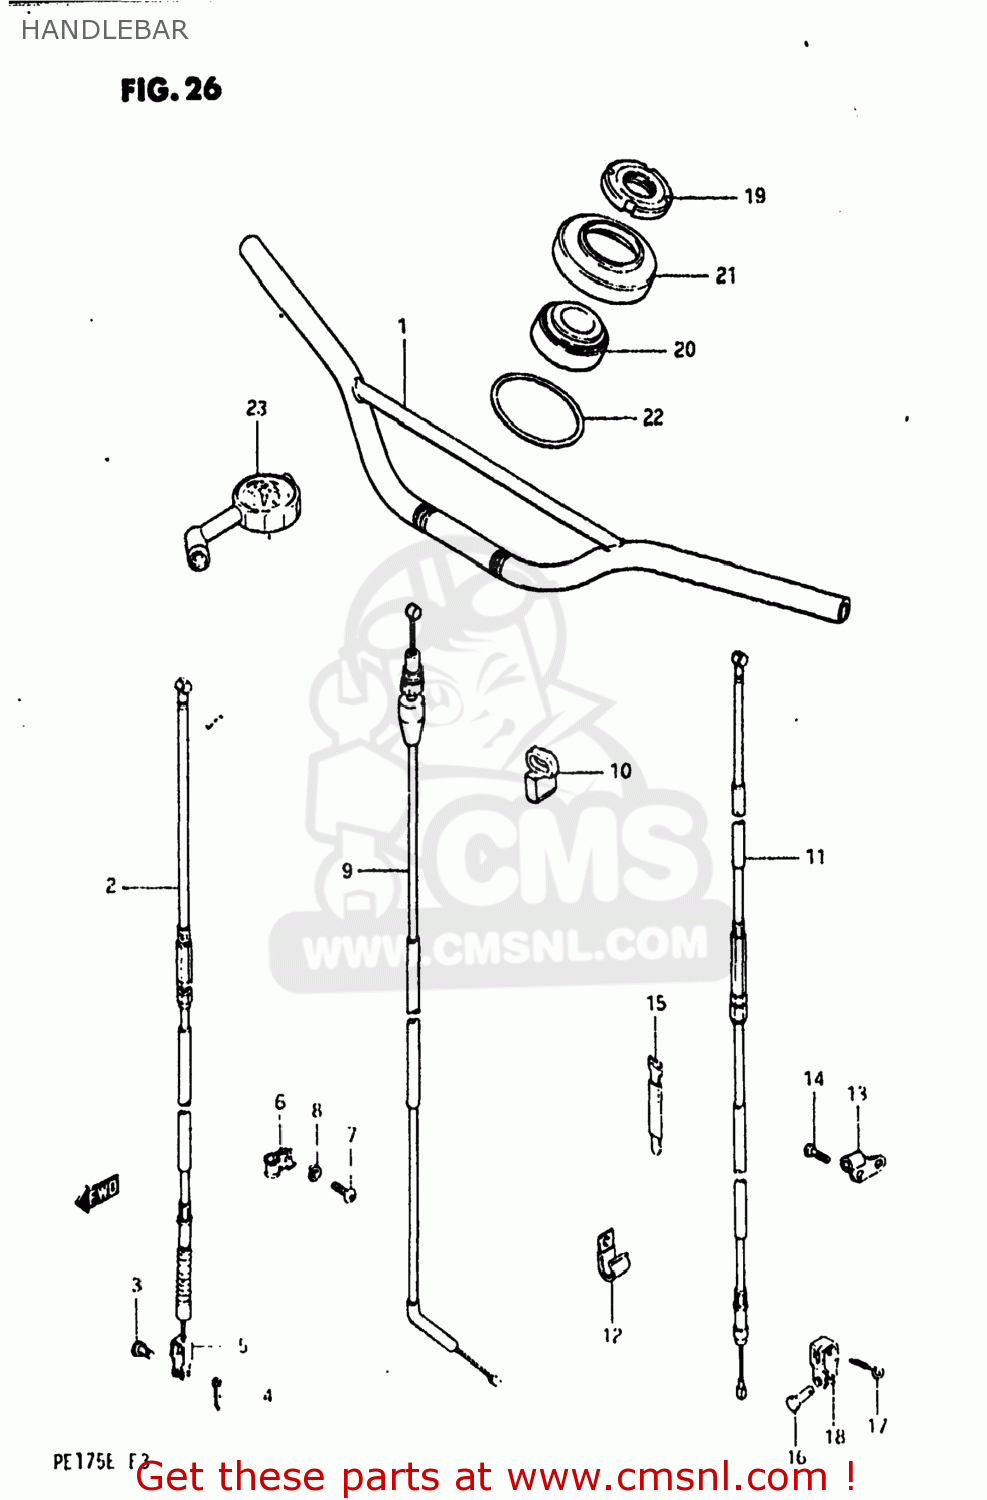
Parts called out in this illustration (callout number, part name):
1	HANDLEBAR
2	CABLE,FR BRAKE
3	PIN(L:13.5)
4	PIN
5	BRAKE CABLE HOOK
6	GUIDE,CABLE
7	SCREW
8	LOCK WASHER
9	CABLE ASSEMBLY,THROTTLE
10	GUIDE,CLUTCH CABLE
11	CABLE,CLUTCH
12	CLAMP
13	STOPPER,CLUTCH CABLE
14	SCREW
15	CLAMP
16	PIN(L:13)
17	PIN
18	HOOK,CLUTCH CABLE
19	NUT,STEERING STEM(25X44X10)
20	TAPER,ROLLER BEARING
21	DUST SEAL,STEERING UPR
22	O RING(D:3.53,ID:69.44)
23	GAUGE ASSY,AIR PRESSURE
